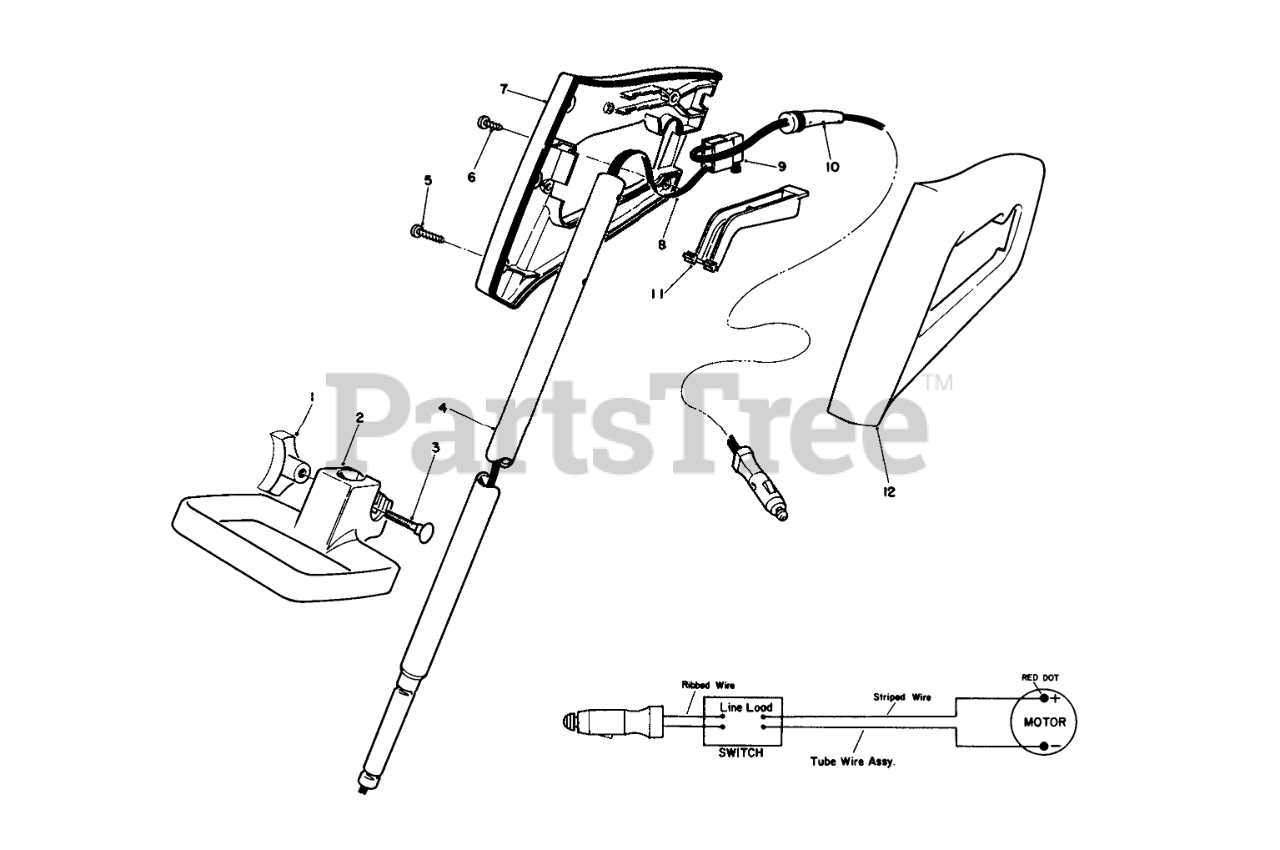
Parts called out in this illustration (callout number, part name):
1	HANDLE KNOB
2	Handle-Adjust
3	BOLT-CARR
4	TUBE-SINGLE
5	Screw
6	SCREW-PPH
7	HANDLE GRIP, RH
8	WIRE ASSEMBLY-TUBE
9	SWITCH
11	TRIMMER-SWITCH BAR
12	HANDLE GRIP, LH
